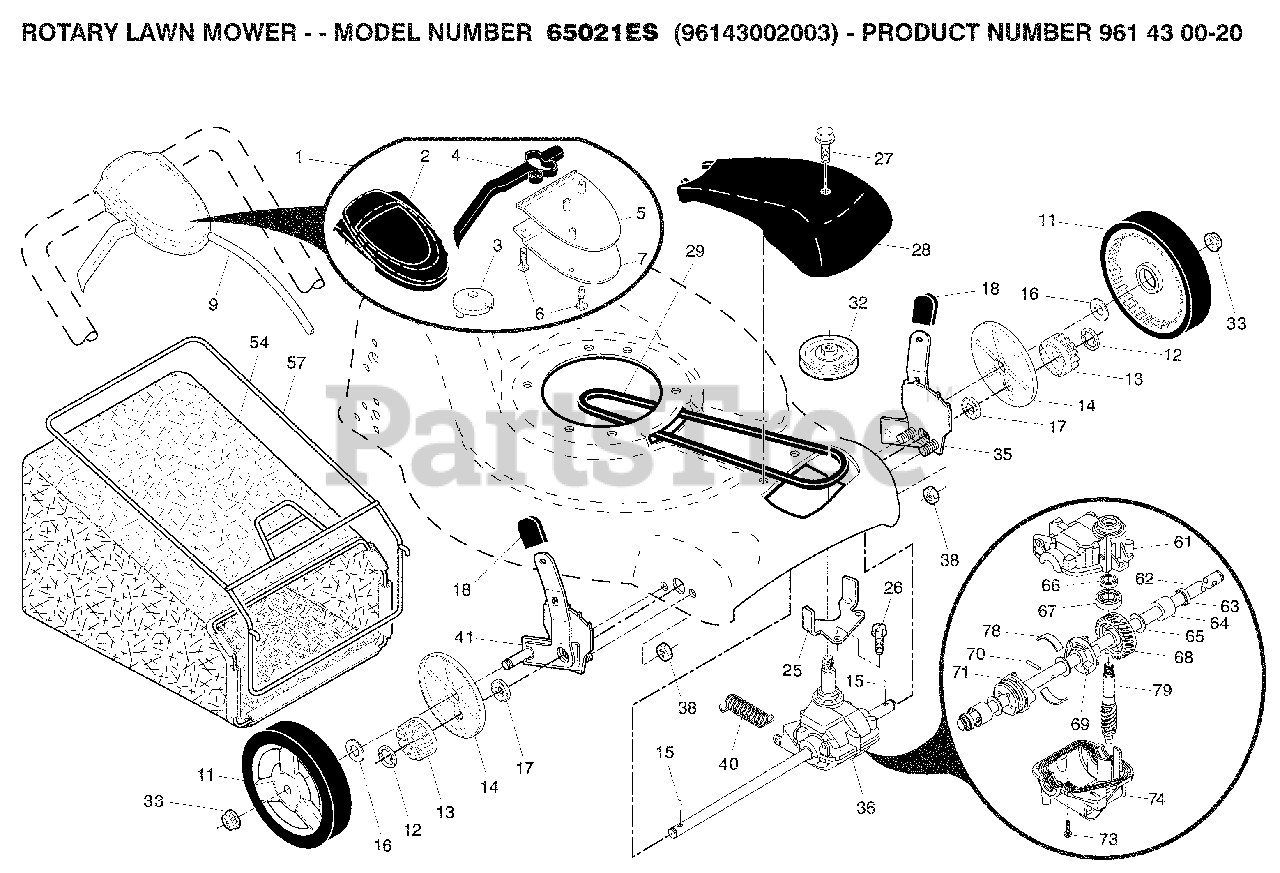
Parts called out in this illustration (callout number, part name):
1	Drive Control Assembly
2	Cover, Drive Control, Upper
4	Lever, Drive Control
5	Cover, Drive Control, Lower
7	Bracket, Drive
9	Cable Assembly, Drive
11	Wheel & Tire Assembly
14	Dust Cover
15	Pawl, Drive
16	Washer 1/2 x 1-1/2 x .134
17	Bearing, Wheel Adjuster
18	Selector Knob
25	Belt Keeper
26	Screw, Hi-Lo Thread
27	Pan Head Tapping Screw #10-24 x 2-3/4
28	Drive Cover
32	Drive Pulley
33	Locknut, Hex
35	Kit, Wheel Adjuster, LH
36	Gearcase Assembly, Complete
38	Locknut, Hex 1/4-20
41	Kit, Wheel Adjuster, RH
54	Grassbag Assembly
57	Frame, Grassbag
61	Case, Upper
62	Shaft, Output
63	Seal, Output Shaft
66	Seal, Worm Shaft
67	Bearing, Ball
68	Gear, 28 Teeth
69	Fixed Dog Clutch
70	Pin
71	Movable Dog Clutch
73	Screw, Case
74	Case, Lower
78	Spring, Leaf
79	Shaft, Worm
